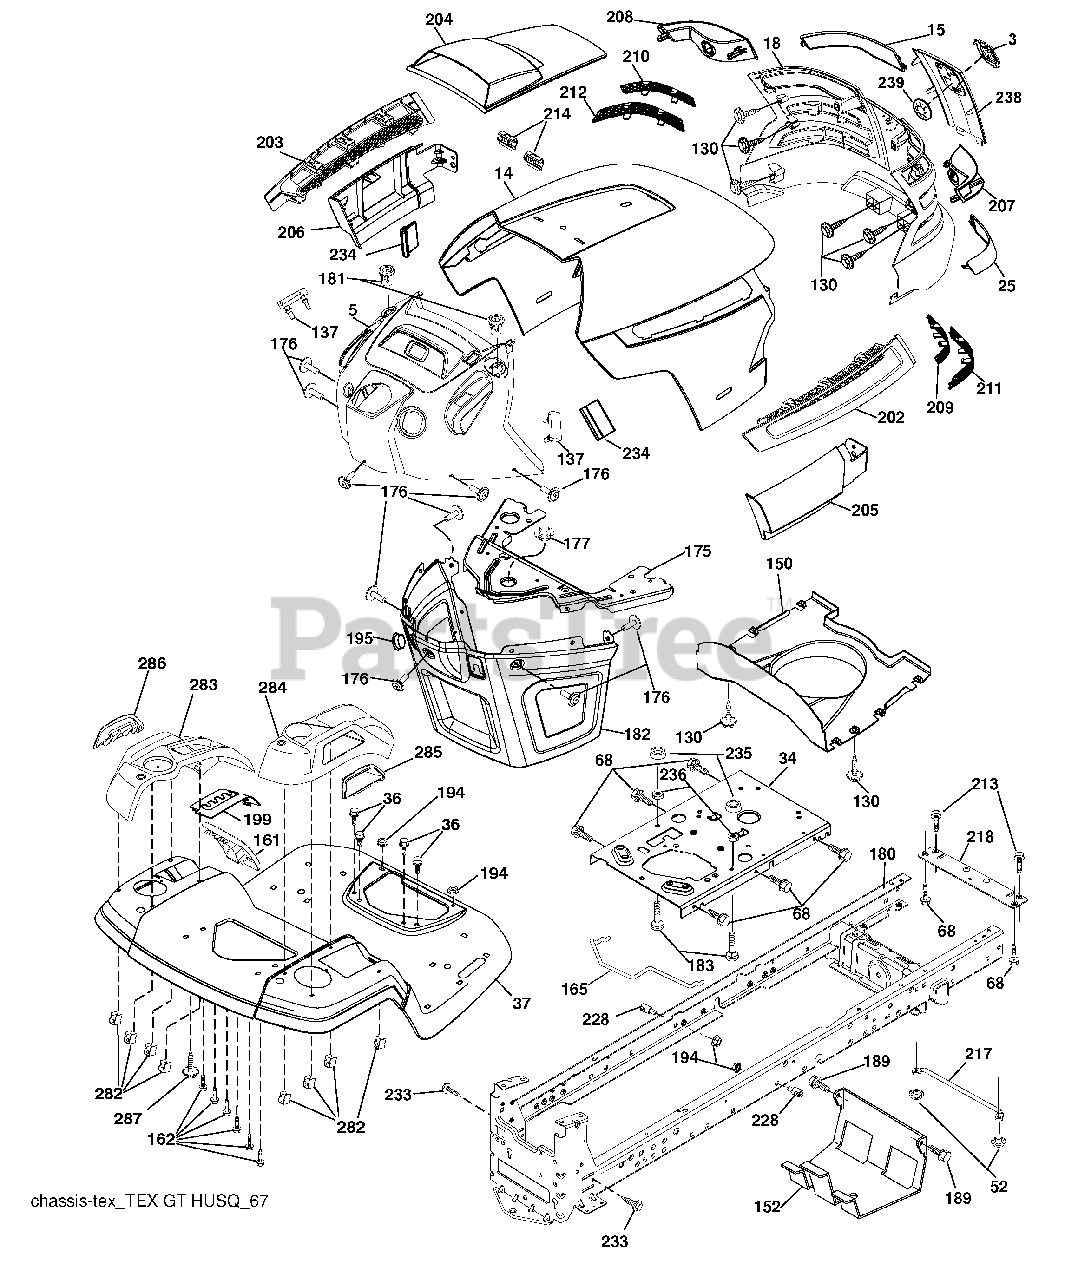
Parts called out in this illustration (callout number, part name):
3	Logo
14	Hood
18	Grille Asm.
34	Plate Engine
36	Screw 5/16-18 x 3/4
52	Nut Lock 5/16-18
68	Screw 5/16-18 x 1/2
130	Screw #10 x 0.750 BOS Thread
137	Bumper Dash
152	Shield Browning
161	Window Fuel
165	Support Tank Rear
175	Crossmember
176	Screw 10-24 x 5/8
177	Bushing Steering
180	Chassis
181	Bushing Mtg. Fender Crgo
182	Dash Lower
183	Bolt Fin Hex 5/16-18 unc x 1-1/4
189	Screw 5/16-18 x 3/4
194	Nut Lock Hex Flange 5/16-18
195	Plug Hole Dash Lower
199	Plate Deck Lift
202	Vent Side Hood RH
203	Vent Side Hood LH
204	Vent Top Hood
205	Skirt Hood Side RH
206	Skirt Hood Side LH
209	Insert Hex Top RH
210	Insert Hex Top LH
211	Insert Hex Bottom RH
212	Insert Hex Bottom LH
213	Bolt 5/16-18 unc x 3/4
214	Clip Retainer Tinner
218	X-Piece Hood Stop
228	Stud Fastner
233	Bolt, Shoulder
234	Bumper Hood
235	Spacer Fender
236	Nut Lock 5/16-18 unc
282	Clip Retainer Console
283	Console Asm. Decklift
284	Console Asm.
285	Console Insert RH
286	Console Insert LH
287	Screw Hex Washead 1/4-20 x 3/8
